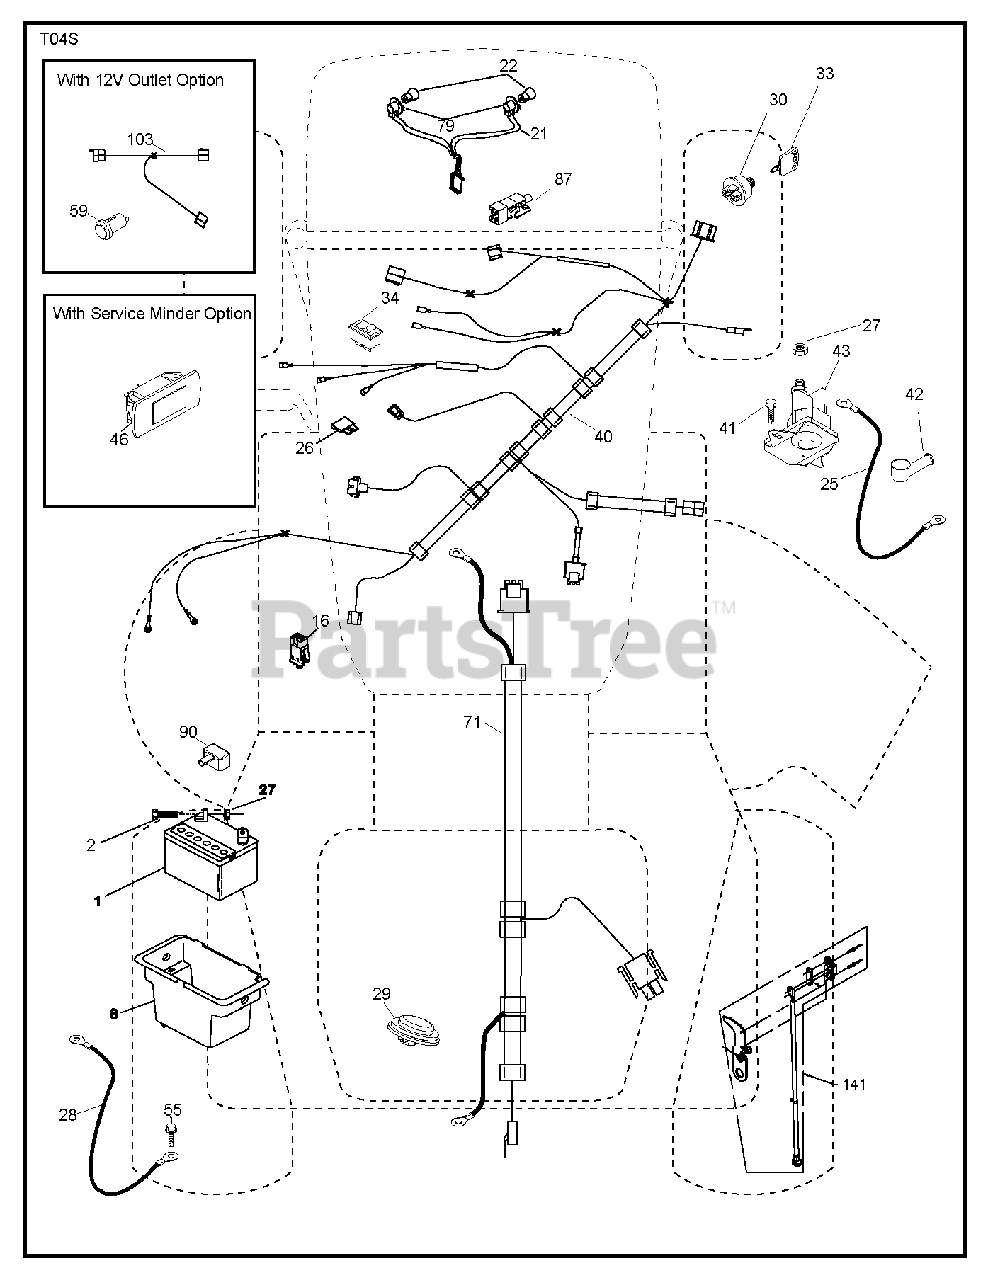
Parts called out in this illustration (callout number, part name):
2	BOLT LT
16	SWITCH INTERLOOK PUSH-IN
22	LIGHTBULB
25	CABLE STARTER
26	FUSE 20AMP
29	SWITCH.SEAT.DELTA.OPC.
30	IGNITION SWITCH
33	KEY/CHAIN.BLISTER.PACK.GEN.USA
34	SWITCH LT
43	SOLENOID.W/BRASS.PLUNG
79	BULB HOLDER ASM.
